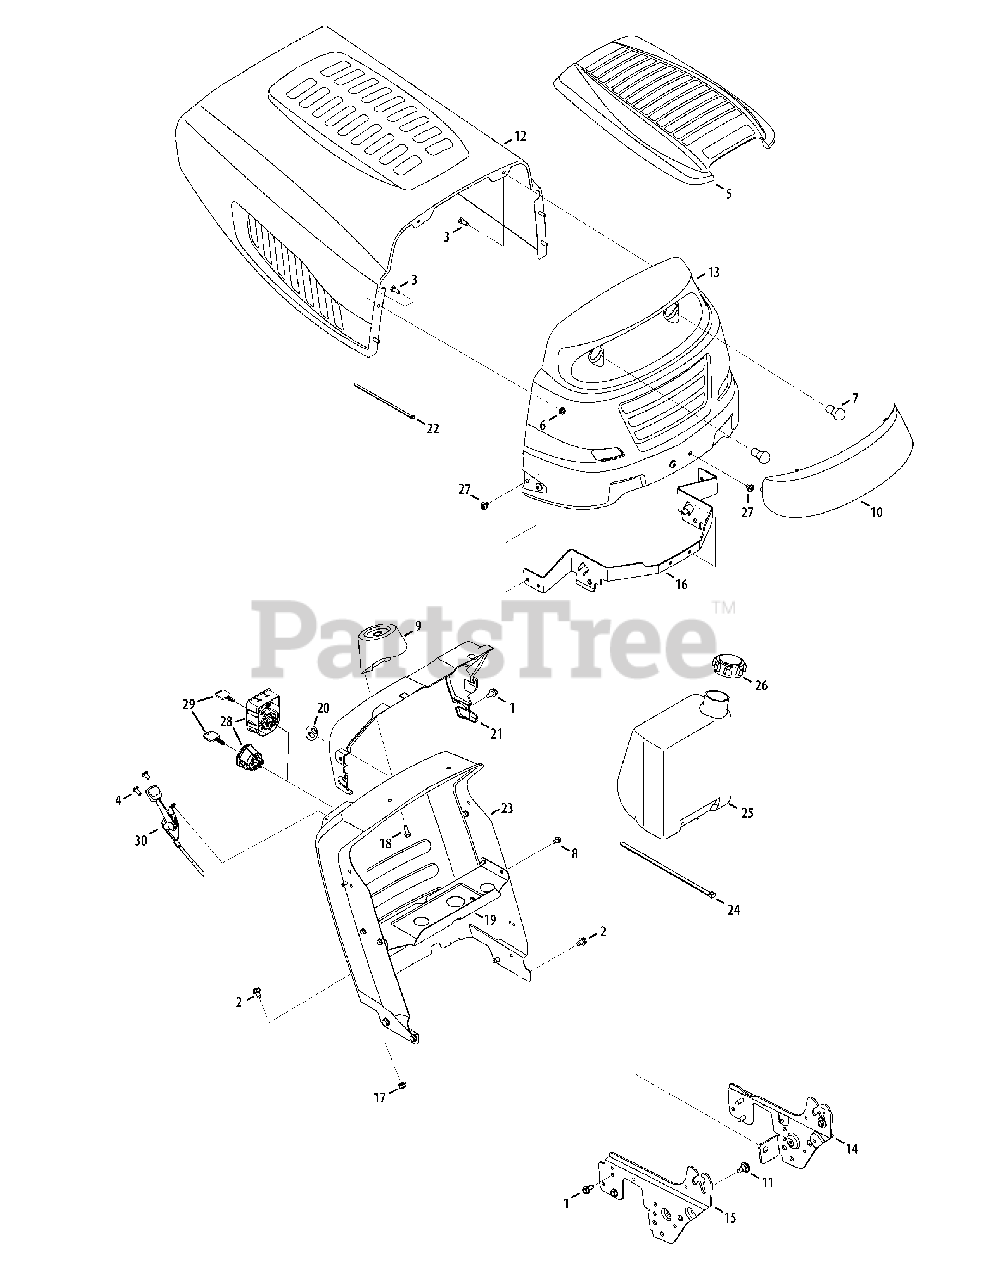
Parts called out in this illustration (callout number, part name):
1	Self-Tapping Screw 5/16-18 x .750
2	Screw, 5/16-18, 0.625
3	Screw, 1/4-20, .620, Gr5
4	Screw, 1/4-20, .500
5	5-Style Hood Cover
6	Nut, Flange Lock, 1/4-20, Gr5
7	Headlamp, 12V
8	Screw, 1/4-20, 0.500
9	Support, Steering
11	Screw, Shoulder, .43 x.29, 5/16-18
17	Flange Lock Nut 5/16-18
18	Screw, 1/4-15, 0.750
20	Dash Plug
21	Collar, Dash
22	Cable Tie
24	Cable Tie, 34.75
25	Fuel Tank, 1.5 gal.
26	Fuel Tank Cap
27	Self-Tapping Screw 5/16-18 x .375
28	Igntion, Switch (No RMC) 3 Pos.
29	Key
30	Throttle/Choke Control, 25"
